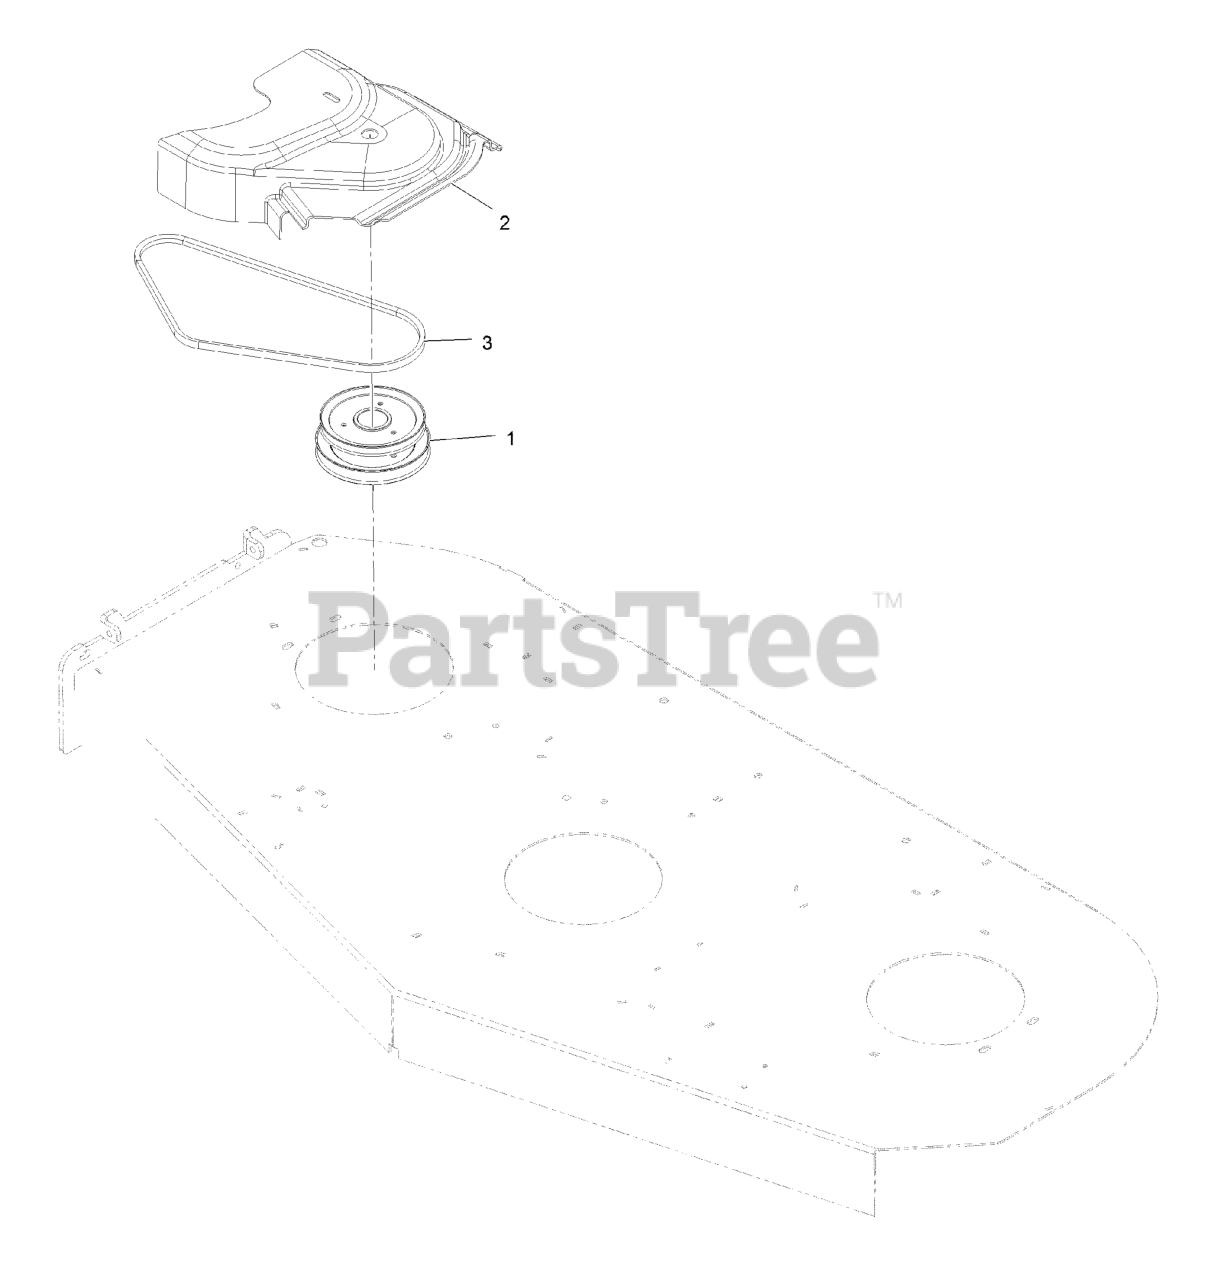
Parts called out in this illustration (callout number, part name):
1	JACKSHAFT, UV DRIVE 724 S
2	COVER,BELT DUV 72
3	BELT, BLOWER DRIVE 72
